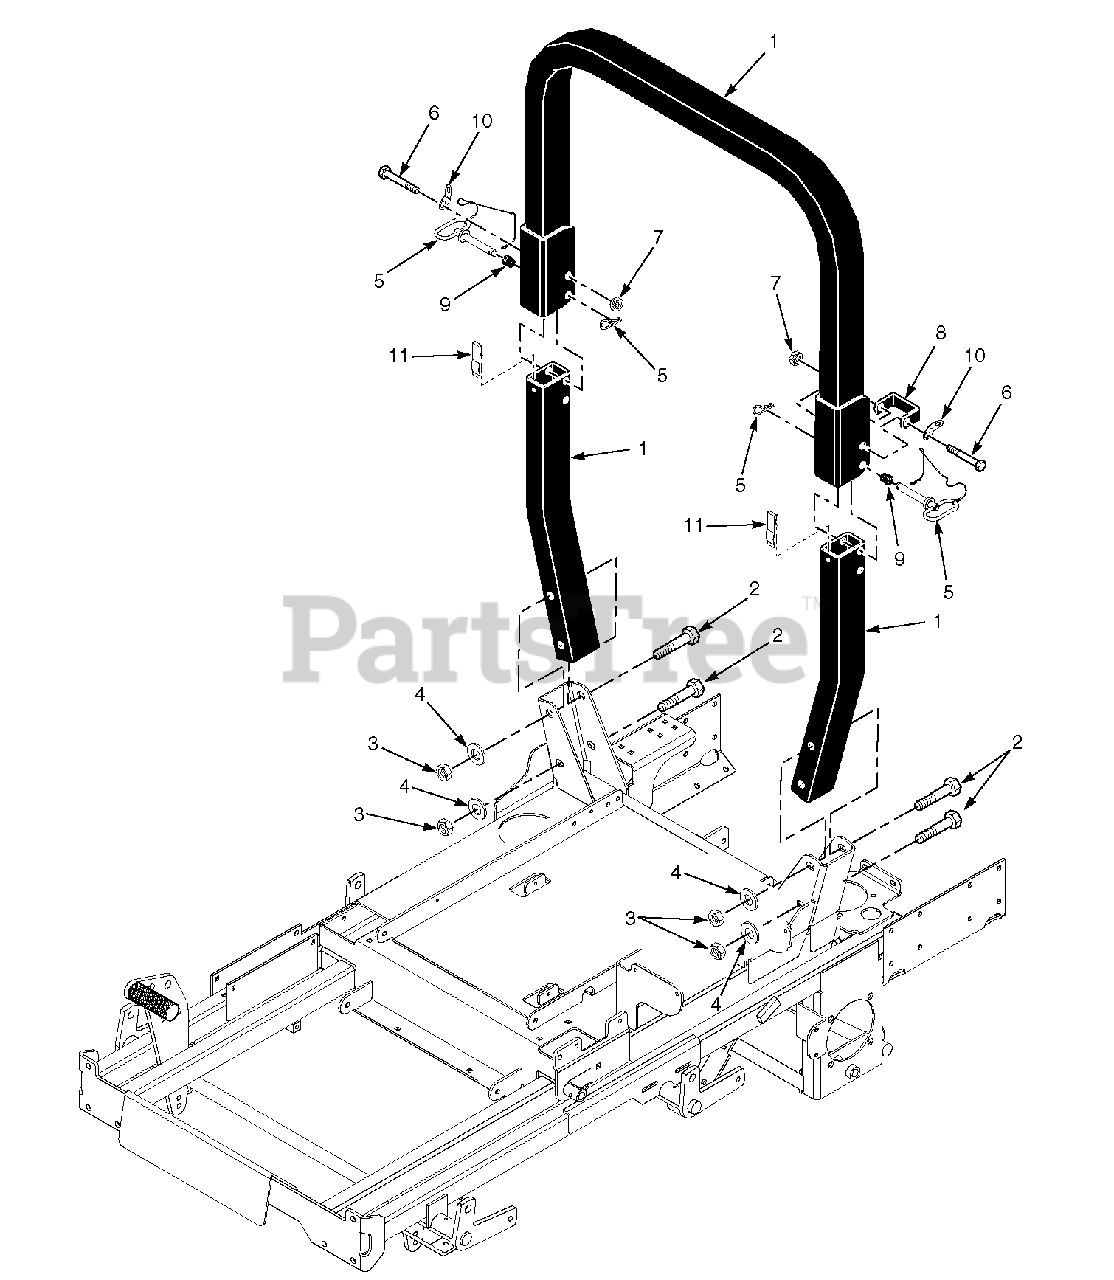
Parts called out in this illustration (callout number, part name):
1	STT, ROPS
2	Bolt, Hex Head 1/2-13 x 4"
3	Nut, Center Lock 1/2-13
4	Flatwasher, 1/2-.562 x 1.375 x .109
5	Pin Assembly
6	Bolt, Hex Head 1/2-13 x 3-3/4"
7	Nut, Center Lock 1/2-13
8	Stop Bracket, ROPS
9	Spring, ROPS
10	Clip, ROPS
11	Spring Clip, ROPS
